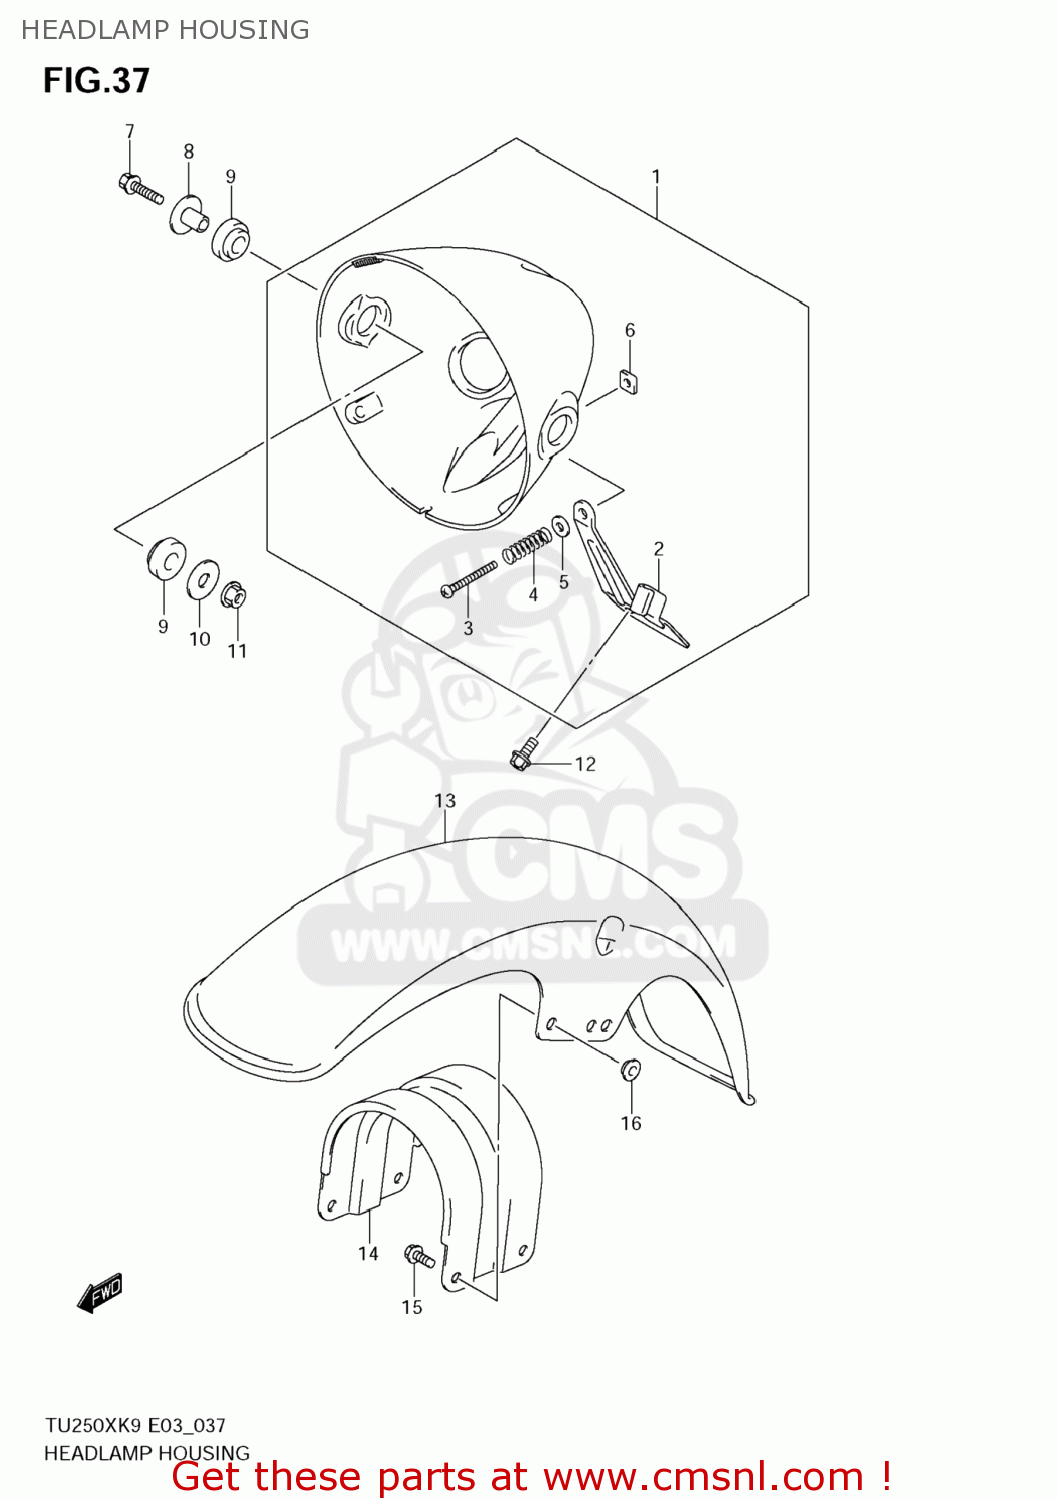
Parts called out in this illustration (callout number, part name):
1	HOUSING SET,HEADLAMP
2	PLATE,HEADLAMP HOUSING
3	SCREW(5X45)
4	SPRING,HEADLAMP ADJUSTER
5	WASHER
6	NUT,HEADLAMP ADJUSTER
7	BOLT
8	SPACER(8.6X12X21.3)
9	CUSHION
10	WASHER(8.5X28X1.6)
11	NUT
12	SCREW
13	FENDER,FR
14	BRACE,FR FENDER
15	BOLT
16	WASHER
